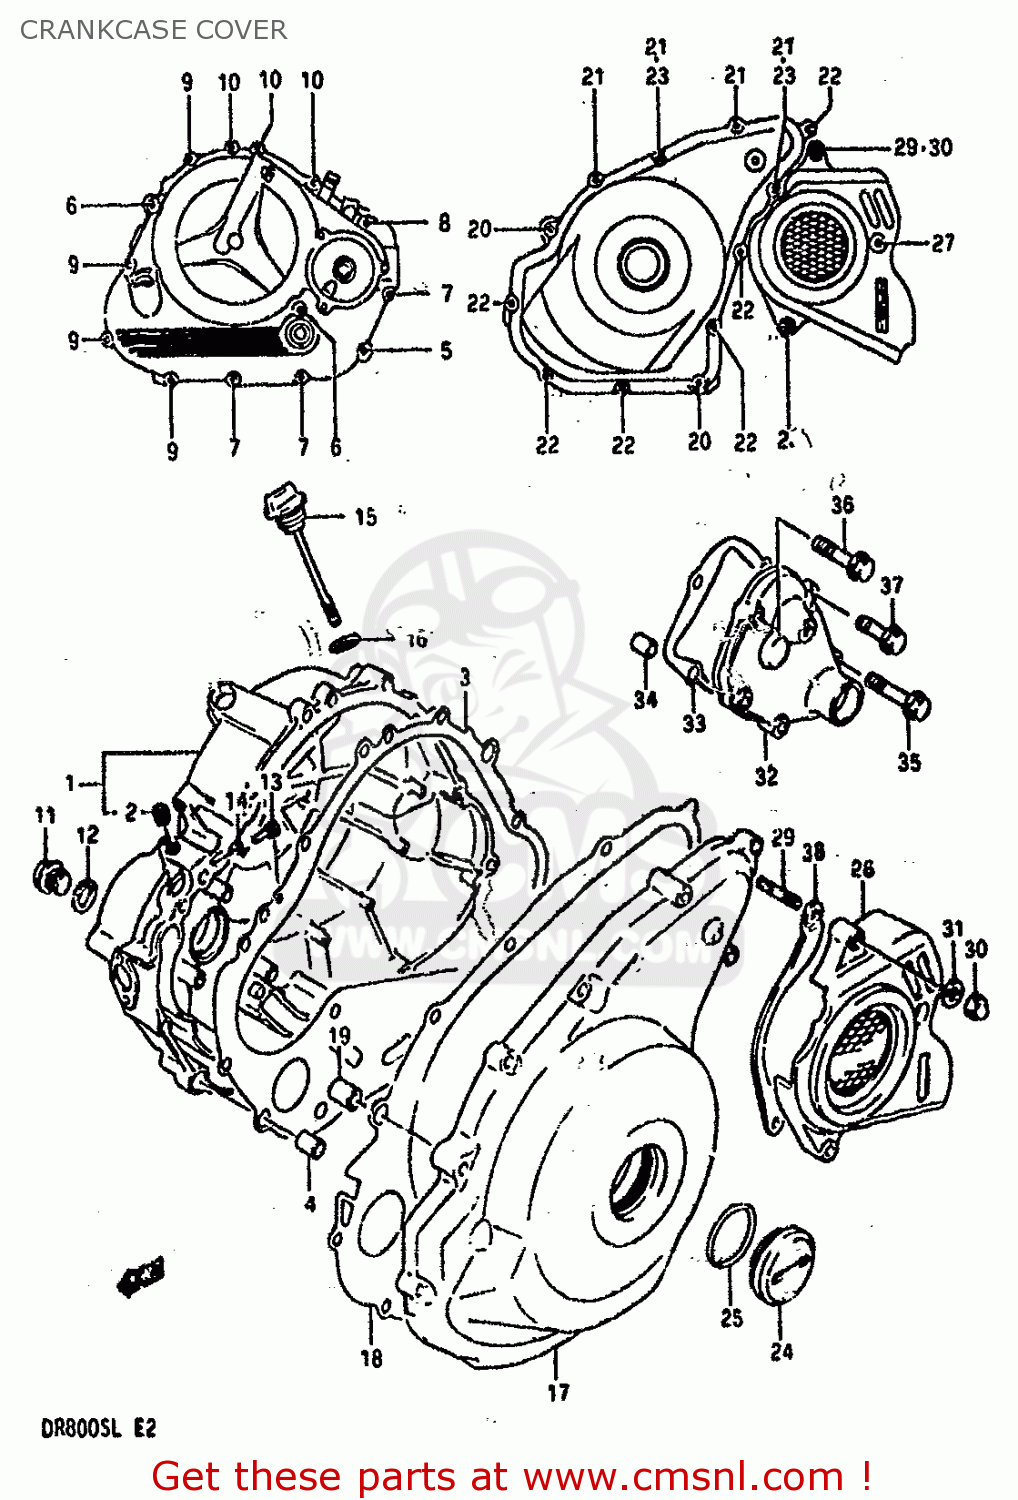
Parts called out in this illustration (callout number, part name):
1	COVER,CLUTCH (GRAY)
2	PLUG
3	GASKET,CLUTCH COVER (NA)
4	PIN
5	BOLT (6X60)
6	BOLT 6X50
7	BOLT
8	BOLT 6X40
9	BOLT 6X30
10	BOLT 6X25
11	PLUG(14X12)
12	GASKET(14X19.2X2) (NAS)
13	JET
14	O RING(D:1.2,ID:4)
15	GAUGE,OIL LEVEL
16	O RING(D:3.1,ID:16.8)
17	COVER,MAGNETO (GRAY)
18	GASKET,MAGNETO COVER (NA)
19	PIN
20	BOLT
21	BOLT 6X35
22	BOLT 6X25
23	GASKET(5.8X13X1.2) (NAS)
24	PLUG
25	O RING(D:3.1,ID:32.7)
26	COVER,ENGINE SPROCKET (GRAY)
27	BOLT 6X30
28	BOLT 6X25
29	BOLT,STUD
30	NUT 6MM
31	WASHER
32	COVER,GEAR SHIFT (GRAY)
33	GASKET,GEAR SHIFT COVER
34	PIN
35	BOLT 6X30
36	BOLT 6X25
37	BOLT
38	PLATE,FR CHAIN GUIDE
